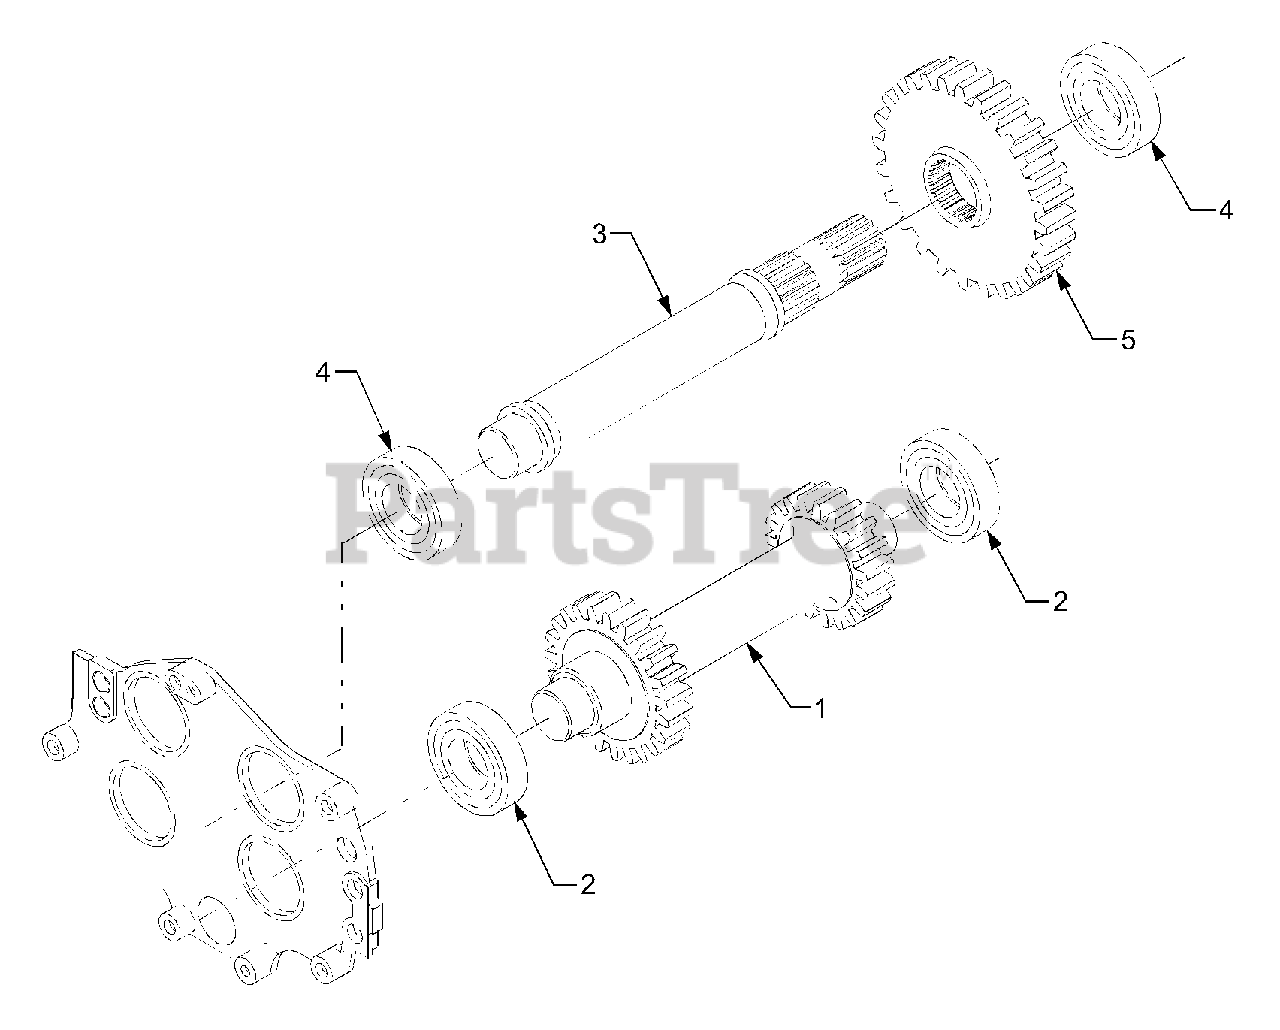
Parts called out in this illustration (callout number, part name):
1	Shaft, 23-19 Gear
2	Bearing, Ball
3	Shaft, Counter (PTO)
4	Bearing, Ball
5	Gear, 33 (PTO)
